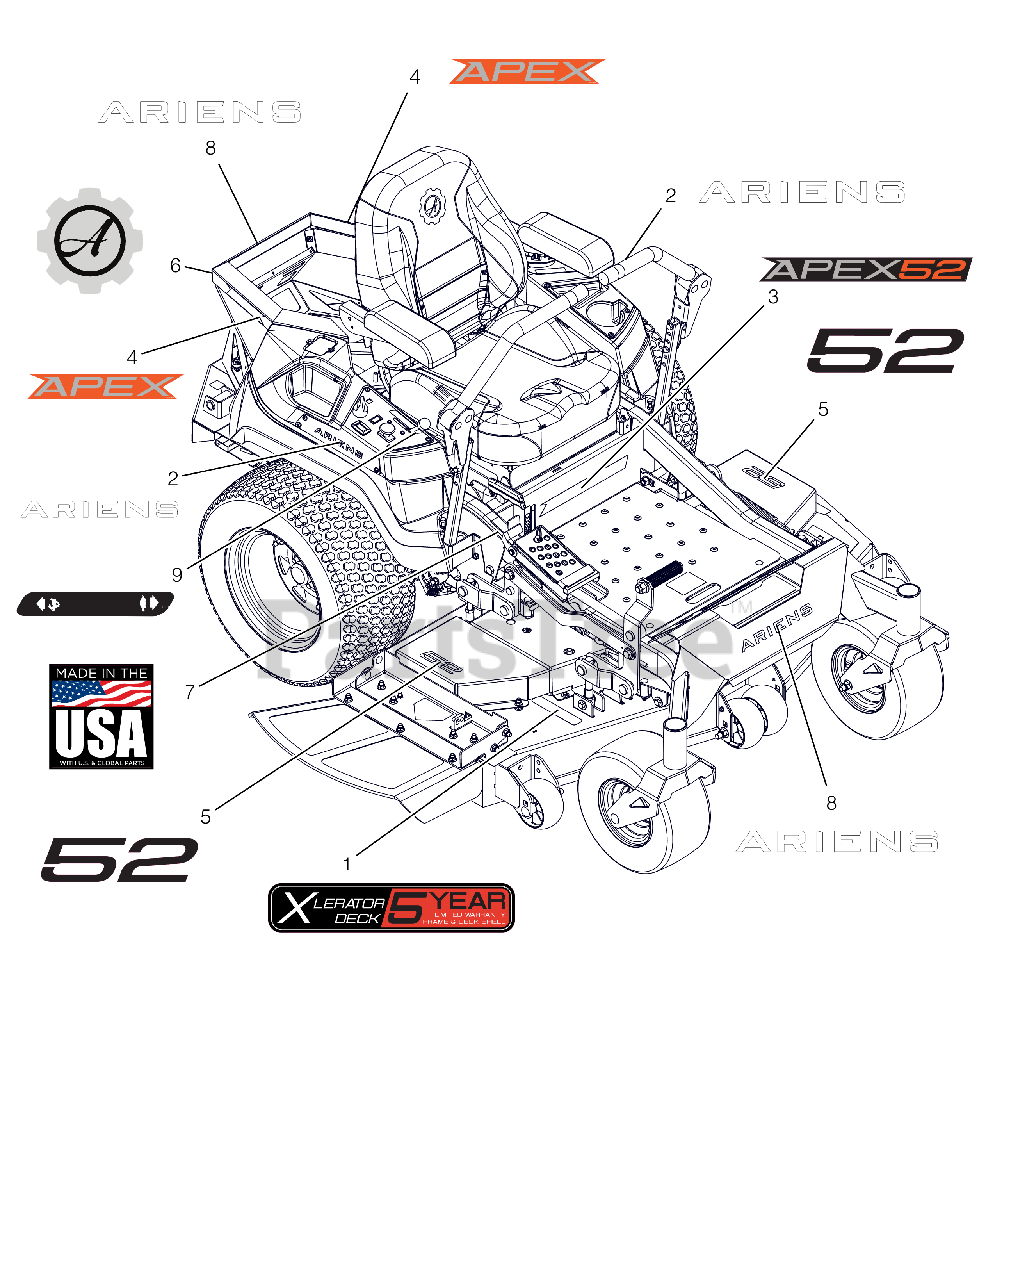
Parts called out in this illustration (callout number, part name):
1	DECAL-ARIENS, DECK 5 YEAR
2	DECAL, ARIENS (6.50")
3	DECAL, 52" APEX KICKPLATE
4	DECAL, APEX FENDER
5	DECAL, BLACK 52
6	DECAL, ARIENS-GEAR BADGE -THK
7	DECAL, MADE IN USA
8	DECAL - ARIENS 9.625"
9	DECAL, DASH DECAL
